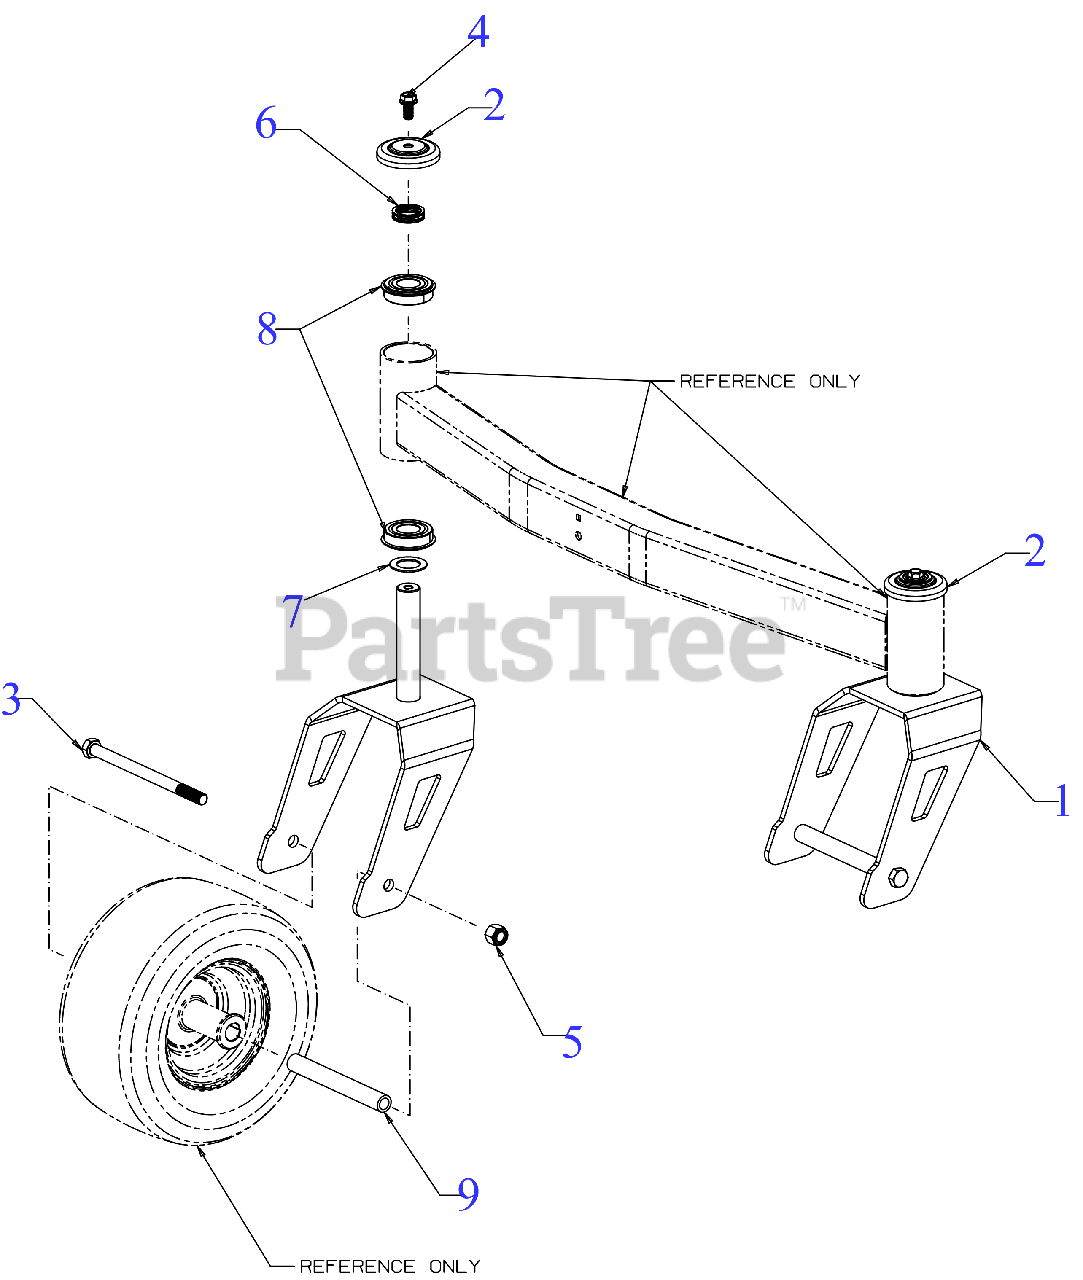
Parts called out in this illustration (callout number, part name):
2	AXLE CAP
3	BOLT 1/2-20 x 7.25 GR5
4	BOLT - 3/8-16:.75:GR5:PATCH LOCK
6	WAVE WASHER
7	WASHER 1.010X1.560X.060
8	BALL BEARING 25X52X15
9	CASTER AXLE SPACER
